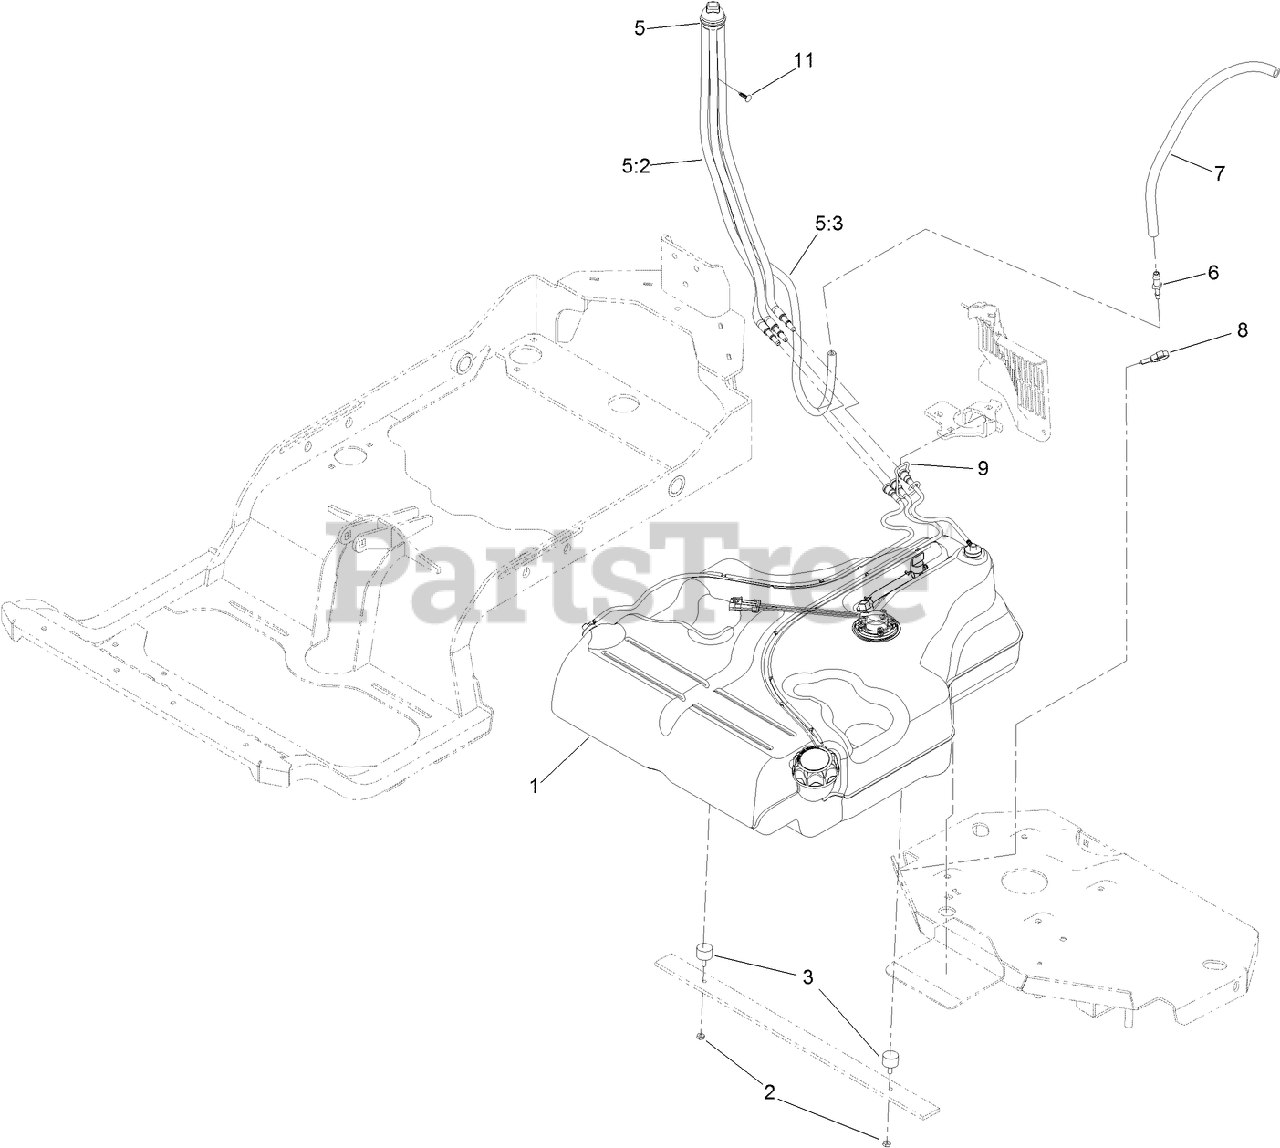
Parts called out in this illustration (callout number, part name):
1	FUEL TANK ASM
2	NUT-JAM
3	BUMPER
5	FUEL MANIFOLD VENT ASM
5:2	HOSE-FUEL
5:3	HOSE-FUEL
6	FITTING-STRAIGHT
7	HOSE-FUEL
8	CLAMP-HOSE
9	RETAINER-LINE, VAPOR
11	PLUG-PLASTIC
